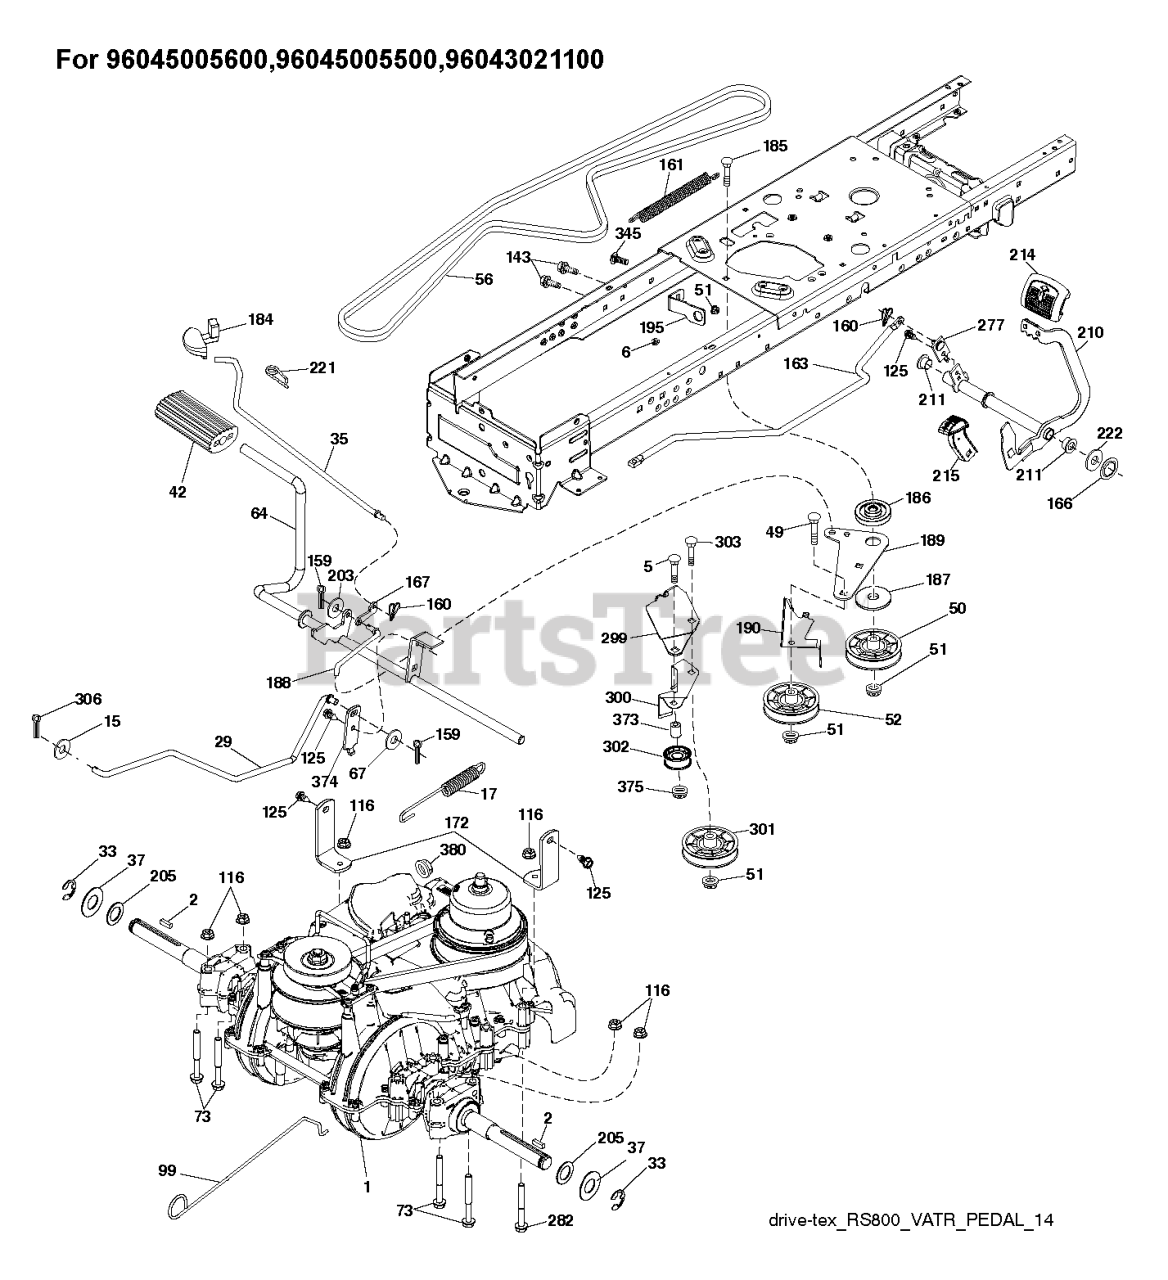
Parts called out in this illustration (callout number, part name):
2	SQUARE KEY
6	BUSHING.SNAP.NYL.BLK.
15	WASHER
17	SPRING.BRAKE.VARIATOR
29	BRAKE.VARIATOR.SD3
35	ROD .BRAKE. PARKING. GT. HUSQ.
37	WASHER.HARDENED
42	PEDAL COVER T
50	IDLER.FLAT.910.OFFSET
51	NUT LOCK FLG 3/8-16 UNC
52	IDLER.V-GROOVE.910.OFFSET
56	BELT.DRIVE.MOWER.TEX.42"
64	SUBASM.SHAFT.PEDAL.BRAKE
67	WASHER.NYLON;13/32X13/16X.109
73	BOLT HEX 5/16-18 GR 5
99	ROD.BYPASS.VARIATOR.GEN2
116	NUT LOCK HEX FLANGE 5/16-18
125	SCREW
143	Screw 5/16-18 x 1/2 Hex, Self Tapping 5/16-18 x 1/2
159	COTTER PIN
160	RETAINER CLIP
161	SPRING, RETURN LT
163	ROD.CONTROL.PEDAL.VARIATOR
166	NUT.PUSH.625
167	LATCH.BRAKE.SPRING
172	STRAP.TORQUE.VARIATOR
184	HANDLE.PARKING.BRAKE.H (BLK)
186	SPACER.RETAINER
187	WASHER 12/32X2X10GA
188	LINK.CLUTCH.GROUND DRIVE.LONG
189	BELLCRANK.GROUND.DRIVE.TEX.
190	KEEPER.BELLCRANK.DRIVE
195	BRACKET.BRAKE.BRAKE.VAR.SD
203	WASHER
210	WELDMENT.PEDAL.VARIATOR
210	WELDMENT.PEDAL.VARIATOR.X431
211	BUSHING.SHAFT.BRAKE.HAND
214	PEDAL.FORWARD.PAD.TEX
215	PEDAL.REVERSE.VARIATOR.MS428
221	RETAINER.SPRING.CLIP.H
222	WASHER 21/32 X 1-1/4 X 10 GA.
277	SUBASM.LINK.ROCKER.PEDAL
282	BOLT HEX FLGHD 5/16-18X3 GR. 5
299	BRACKET.MOUNT.IDLERS
300	KEEPER.IDLERS.REAR.VARIATOR
301	PULLEY.IDLER.V-GROOVE
303	BOLT CARRIAGE
306	PIN COTTER
373	SPACER.IDLER
374	ARM.CONTROL.BRAKE
380	NUT.FLG.NYLOCK.1/4-20.GR.G.ZY
